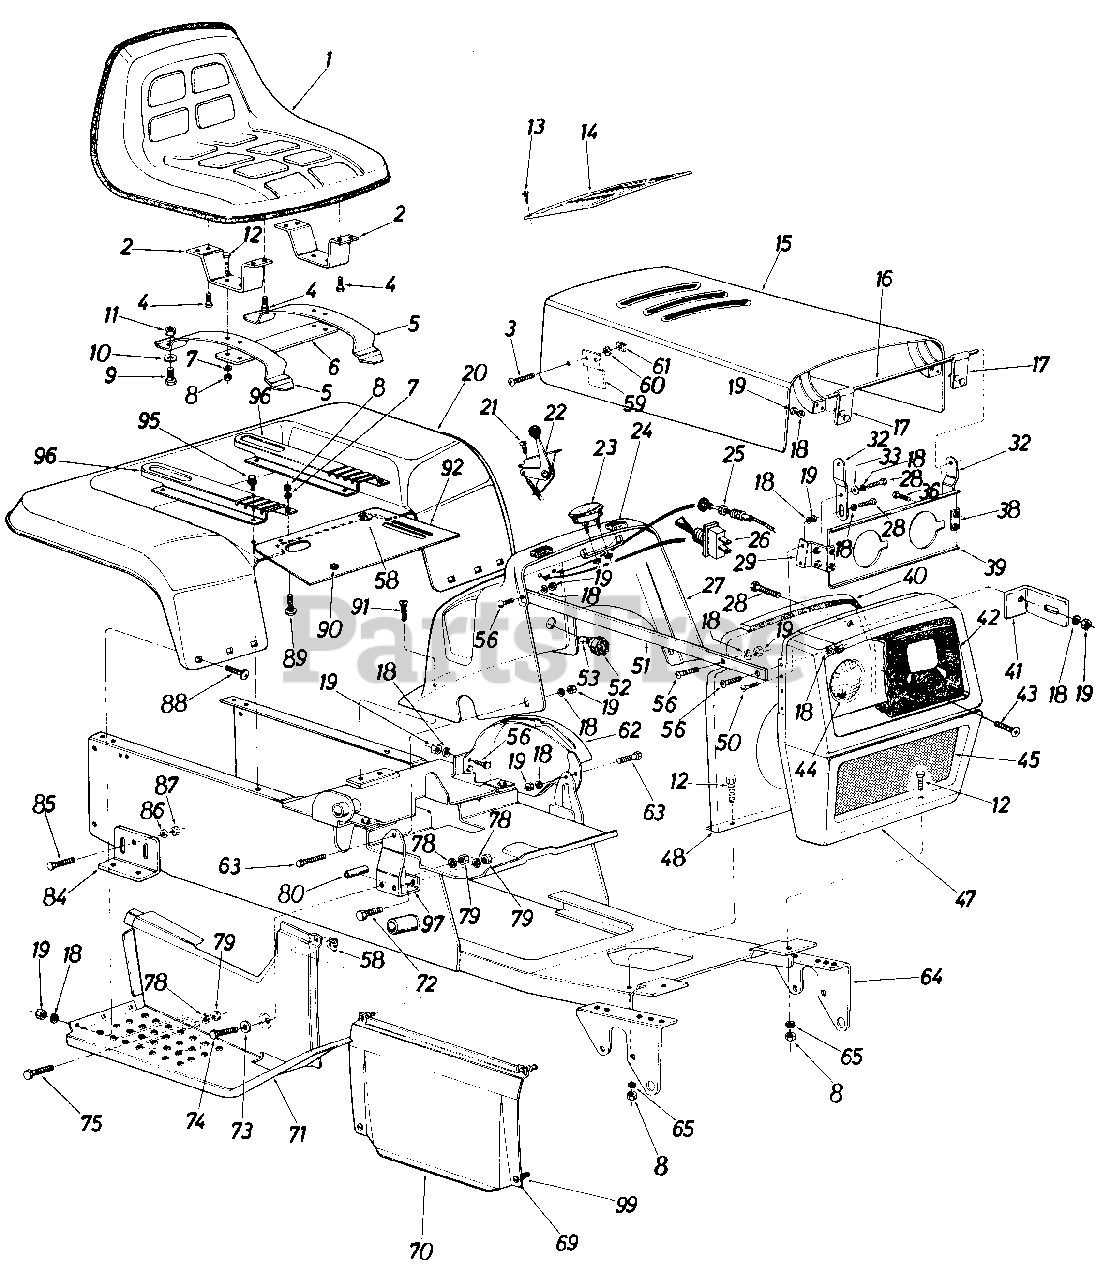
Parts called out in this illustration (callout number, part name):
1	Seat Ass'y.
2	Seat Support Brkt.
3	Truss Hd. Mach. Scr. #10-24 x.38" Lg.
4	Hex Wash. Hd. Self-Tap Scr. 3/8-16 x .75" Lg.
7	L-Wash. 5/16" Scr.
8	Hex Nut 5/16-18 Thd.
9	Nylon Scr 1/2-13 x .75" Lg.
10	Fl-Wash .531 I.D. x .930 O.D.
11	Hex Cent. L-Nut '/2-13 Thd.
12	Hex Scr. 5/16-18 x .75" Lg.
13	Self-Tap Oval Hd. Scr. 1/2" Lg.
14	Dash Panel Cover
15	Hood Ass'y.
16	Hinge Rod
17	Hood Hinge Ass'y.
18	L-Wash. 1/4" I.D.
19	Hex Nut 1/4-20 Thd.
20	Rear Fender
21	Fl-Hd. Truss Scr. #10 x .62" Lg.
22	Throttle Control
23	Ammeter
24	Rubber Bumper
25	Choke Control
26	Light Switch
27	Dash Panel
28	Hex Scr. 1/4-20 x .62" Lg.
29	Hood Support Brkt. Ass'y.-R.H.
36	Hex Scr. 1/4-20 x .38" Lg.
38	Hood Support Brkt. Ass'y.-L.H.
41	Heat Sheild Brkt.
42	Head Lamp Bezel
43	Truss Mach. Scr. #10-24 x .50" Lg.
44	Head Lamp
45	Grille Screen
50	Truss Mach. Scr. 1/4-20 x .75" Lg.*
51	Grille Strap
52	Ignition Switch
53	Ignition Key
56	Hex Scr. 1/4-20 x .75" Lg.*
58	Clip-On Receptacle
59	Hood Spring
60	L-Wash. #10
61	Hex Nut #10-24
62	Speed Control Guide
63	Truss Mach. Scr. 1/4-20 x .75" Lg.*
64	Frame Ass'y.
65	Bell-Wash. 5/16" I.D.
69	1/4-Turn Stud
70	Hood Lower Side Panel
71	Foot Step Panel Ass'y.-R.H.
72	Hex Scr. 3/8-16 x 1.00" Lg. Grade 5
73	Fl-Wash. .385 I.D. x .62 O.D.
74	Hex Scr. 3/8-16 x 3.00" Lg.*
75	Hex Scr. 3/8-16 x 1.00" Lg. Grade 5
78	L-Wash. 3/8" I.D.*
79	Hex Nut 3/8-16 Thd.*
80	Spacer .375 I.D. x .62 O.D. x 2.00" Lg.
84	Transaxle Support Brkt.
85	Rd. Hd. Rib Neck Scr. 3/8-24
86	L-Wash. 3/8" Scr.*
87	Hex Nut 3/8-24 Thd.*
88	Carr. Bolt 1/4-20 x .50" Lg.*
89	Carr. Bolt 5/16-18 x .62" Lg.*
90	Snap Bushing
91	Fl-Hd.Self-Tap Scr. 1/4-20 x .62" Lg.
96	Seat Adjustment Brkt.
